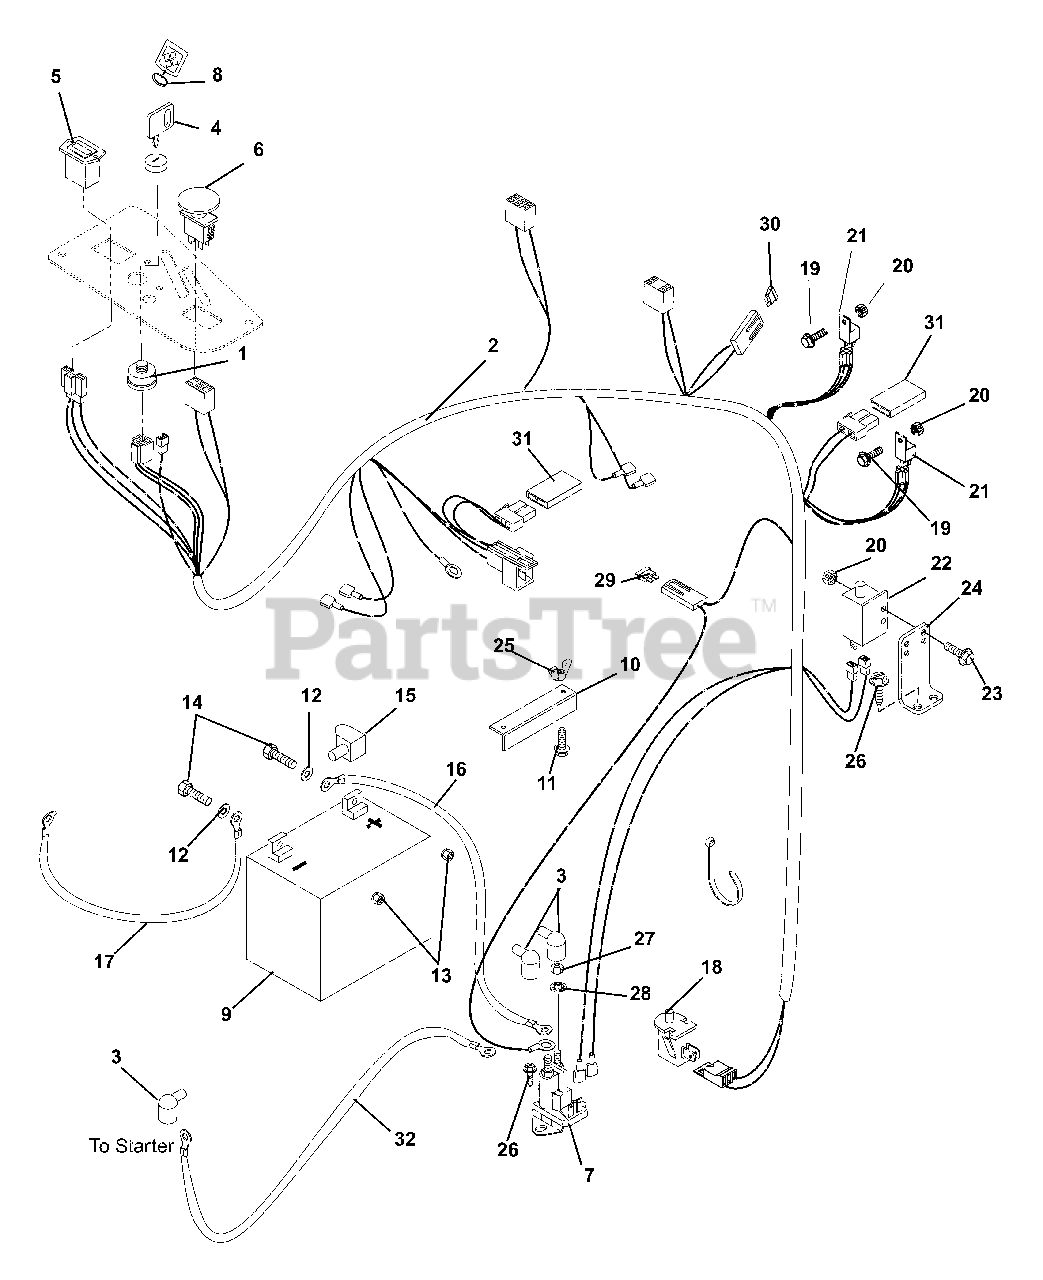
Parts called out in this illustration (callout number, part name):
1	SWITCH, IGNITION
2	HARNESS,CZ-EYEQ REMOTE SOL.
3	BOOT, EYELET TERMINAL
4	KEY, W/ SHIELD
5	HOURMETER-QUARTZ 80VDCMAX
6	SWITCH, CLUTCH
7	SOLENOID
8	KEY CHAIN
9	BATTERY, 300 CCA 10U1L
10	HOLD DOWN
11	BLT-RDHDSQNK .25-20X7.50 GR2YZ
12	@WSHR-FL-STL.281X.62X.065 YWZC
13	@NUT-LK-TOP-FLG .25-20 YWZC
14	@BLT-HEX .25-20X.75 GR5 YWZC
15	INSULATOR
16	CABLE, POS. BAT. 9.00"
17	CABLE, NEGATIVE BATTERY 24.00
18	SWITCH- SNAP MTG N.O.
19	@SCR-MCH 10-24X.50 HWH YWZC
20	@NUT-LK-NYL 10-24 W/INSRT YWZC
21	RELAY
22	SWITCH- SINGLE POLE N.O.
23	@SCR-MCH 10-24X.75 HWH YWZC
24	BRAKE SWITCH MOUNT - BLACK
25	NUT-LK WING .250-20 YWZC
26	@SCR-TAP .25-20X.50 HWH TR YWZ
27	NUT-JAM .31-24 YWZC
28	@WSHR-LK .31X.078 REG YWZC
29	FUSE-25 AMP ATC TYPE
30	FUSE 20AMP
31	DIODE, CONNECTOR SHELL
32	CABLE, STARTER .31X23.00X.31
